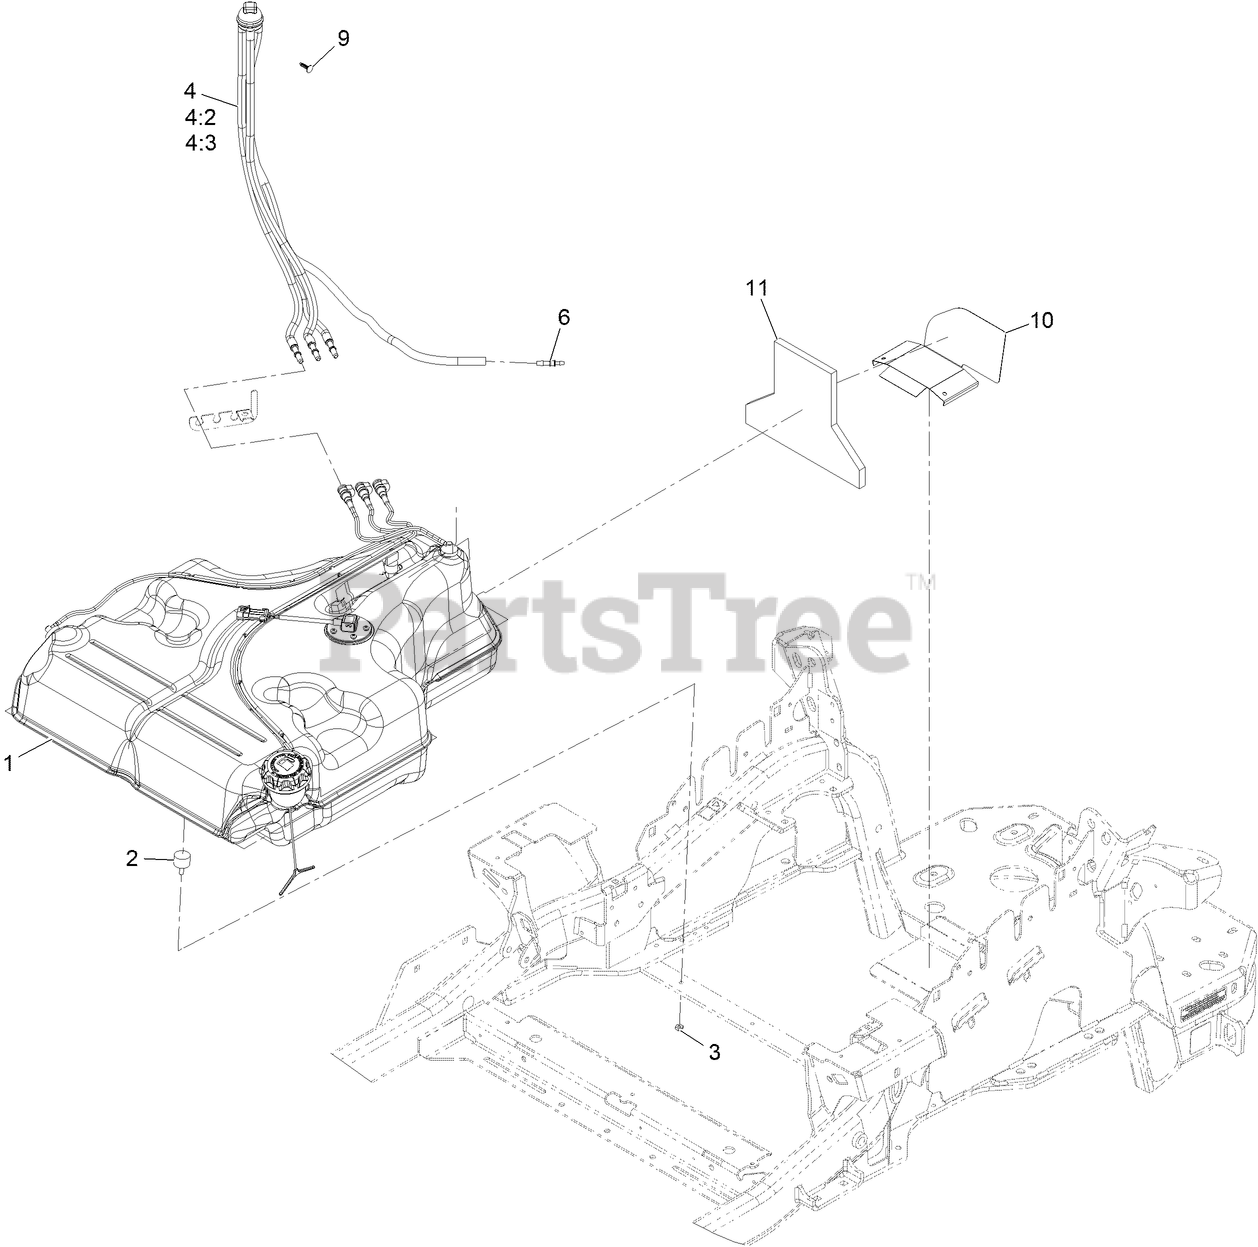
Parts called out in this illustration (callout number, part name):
1	FUEL TANK ASM
3	NUT-JAM
4	FUEL MANIFOLD VENT ASM
4:2	HOSE-FUEL
4:3	HOSE-FUEL
6	BARB-FUEL
9	PLUG-PLASTIC
10	GUARD-EXHAUST
11	INSULATION-FOAM, FUEL TANK
